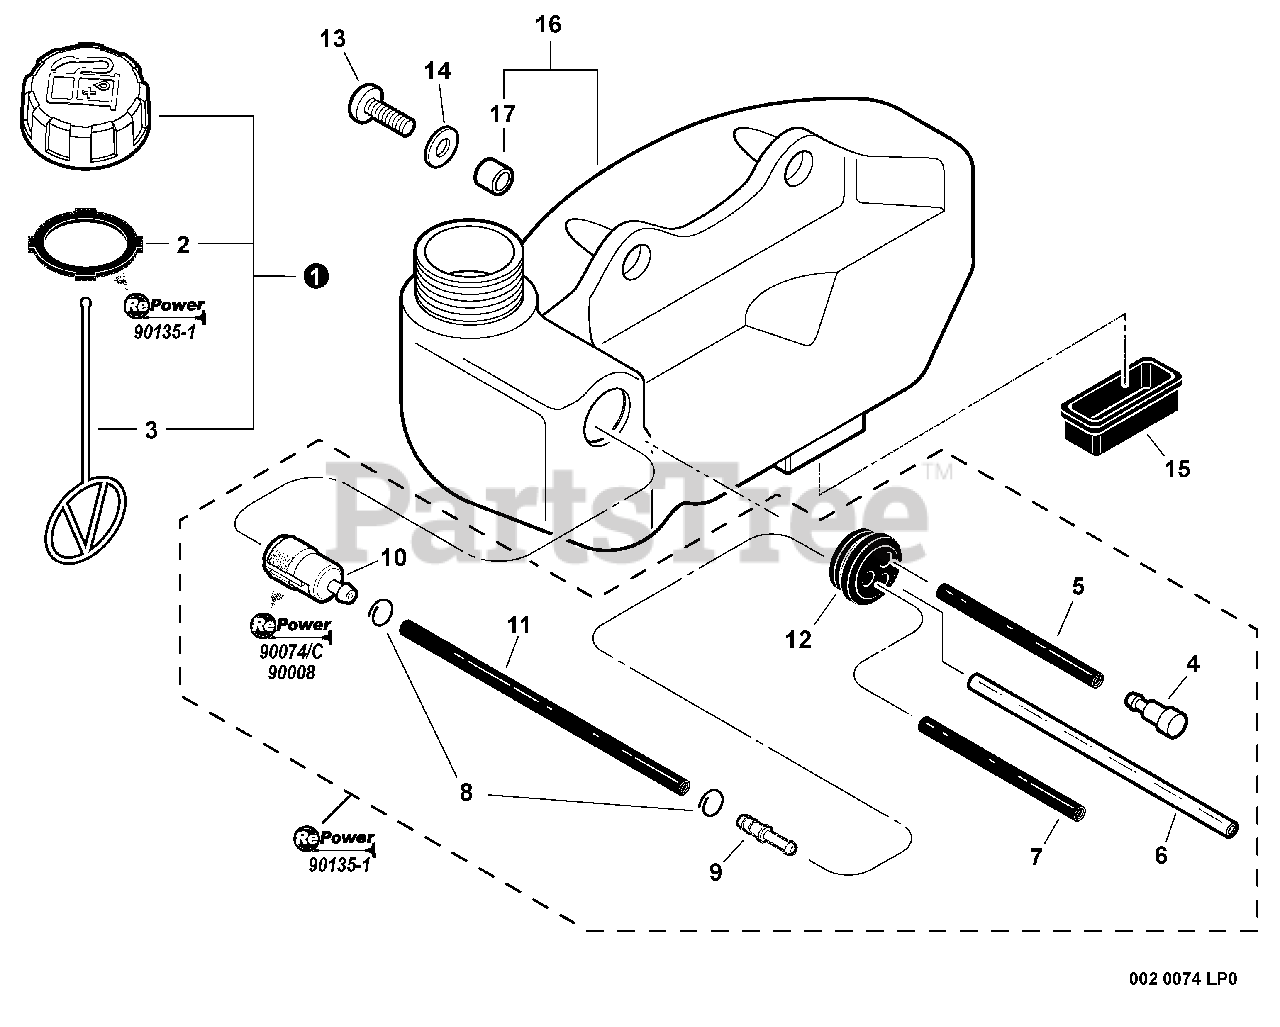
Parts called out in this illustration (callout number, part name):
1	CAP ASSY, FUEL
2	GASKET, FUEL CAP
3	CONNECTOR, CAP L= 100 MM
4	VENT ASSY
5	PIPE, FUEL 3x-5x-70 BLACK
6	PIPE, FUEL RETURN 3×6×110
7	PIPE, FUEL 3×5×87 BLACK
8	CLIP Ø6
9	CONNECTOR, PIPE Ø5ר3.5
10	FILTER, FUEL
11	PIPE, FUEL 3×5×115
12	GROMMET, FUEL Ø5
13	SCREW 5×15
14	WASHER 5.5×12×0.8
15	CUSHION, FUEL TANK
16	TANK ASSY, FUEL
17	SPACER 6.2×7.8×6
18	FUEL SYSTEM KIT
19	TUNE-UP KIT - REPOWER
20	FILTER KIT - REPOWER
